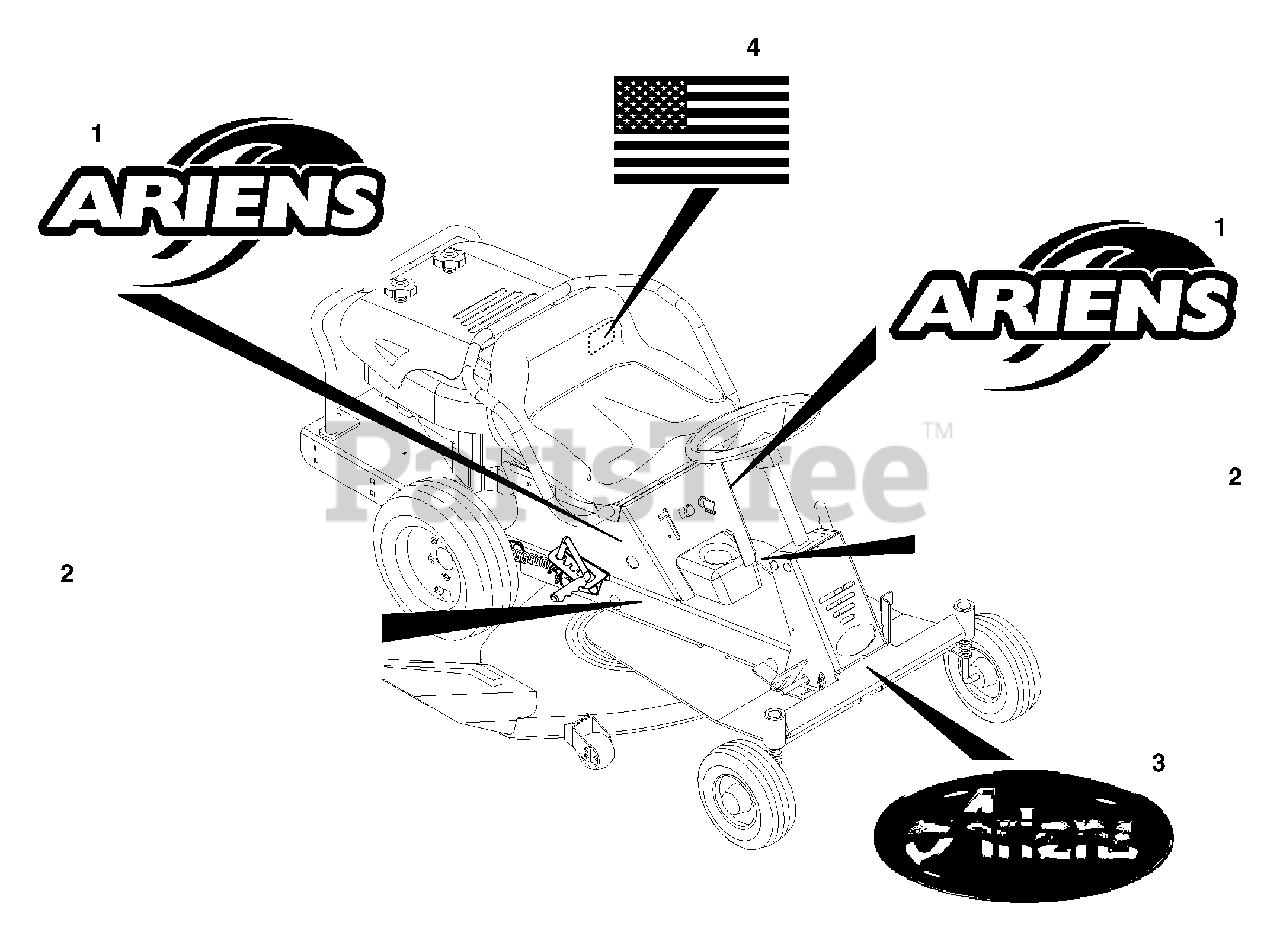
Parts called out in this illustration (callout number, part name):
1	DECAL-ARIENS ZOOM
2	DECAL-1028 RER ARIENS
3	DECAL-ARIENS JEWEL
4	DECAL, AMERICAN FLAG
